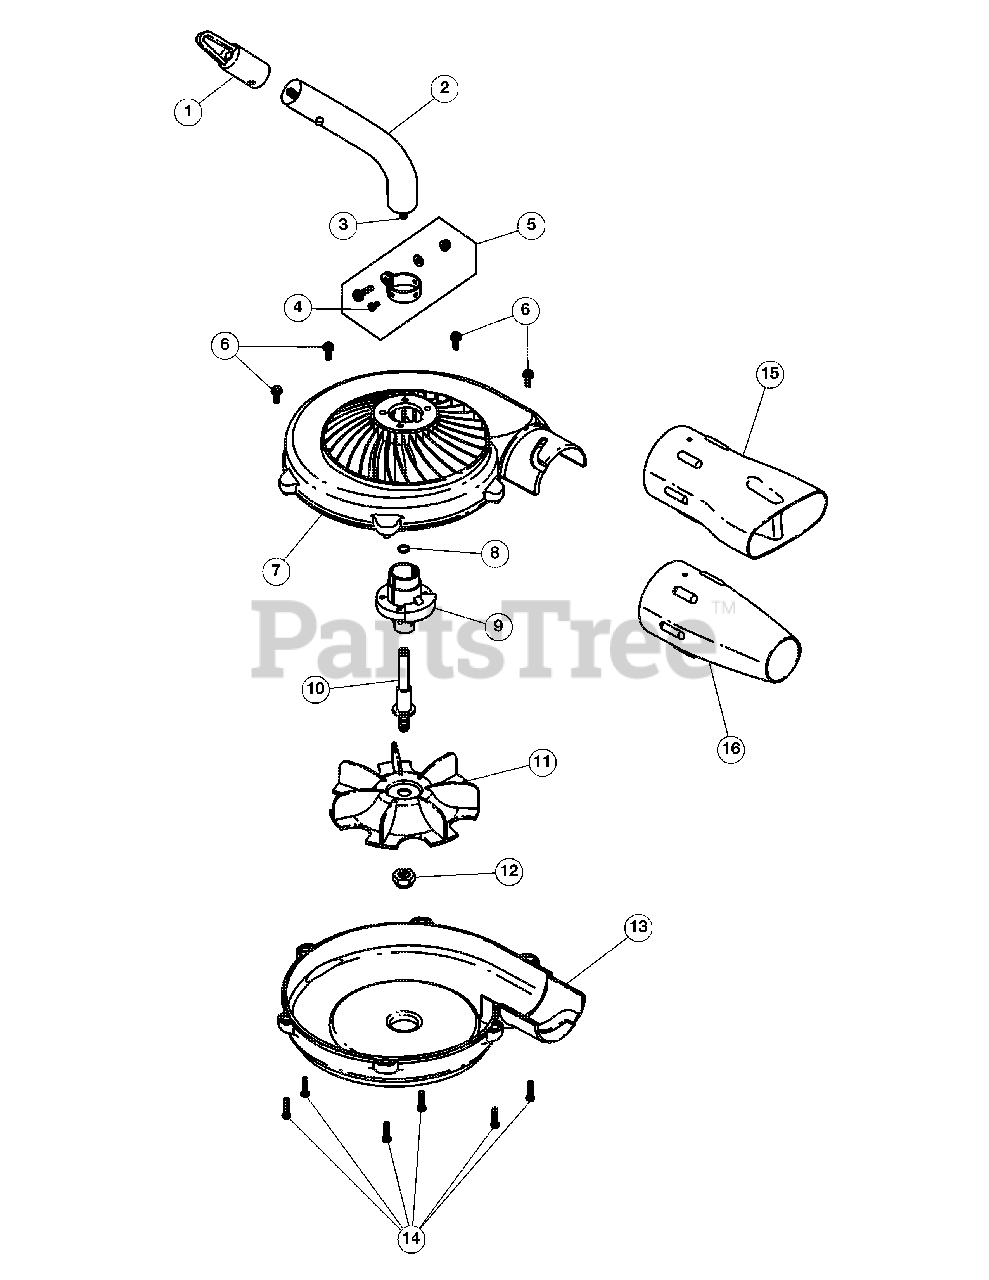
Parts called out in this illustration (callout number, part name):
1	Hanger
2	Drive Shaft Housing Assembly
3	Drive Shaft Assembly
4	Anti-Rotation Screw
5	Lower Clamp Assembly (Incl. 4)
6	Mounting Screw
7	Upper Housing
8	Palnut
9	Bushing Assembly Housing
10	Shaft Impeller
11	Impeller
12	Nut and Washer
13	Lower Housing
14	Mounting Screw
15	Flare Nozzle
16	Concentrator Nozzle
